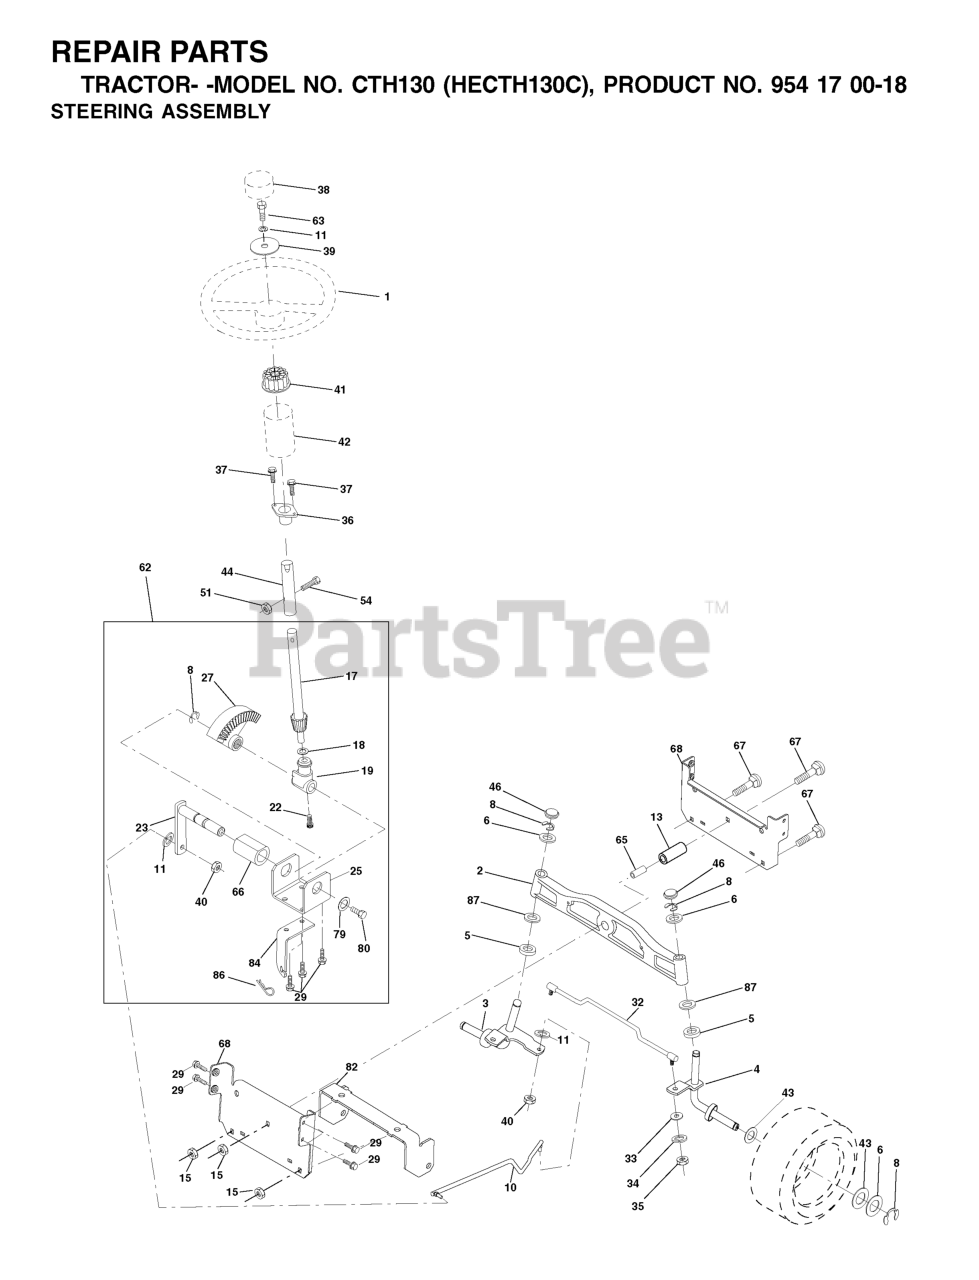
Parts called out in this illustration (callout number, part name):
1	STEERING WHEEL
2	AXLE ASM
3	SPINDLE.ASM.LH.15"TIRES
4	SPINDLE.ASM.RH.15"TIRES
5	THRUST WASHER
10	DRAGLINK.15".TIRES
11	WASHER, LOCK 3/8
13	TUBE, PIVOT AXLE
15	NUT
17	SHAFT ASM STEERING
18	THRUST WASHER
19	STEERING SHAFT SUPPORT
22	SCREW.HX.WSH.HD
23	SHAFT ASSY PITTMAN
25	BRACKET STEERING
27	GEAR.SECTOR
29	SCREW 3/8-16X3/4
32	ROD.ASM.TIE.BALL.JOINT.NOVAN
33	WASHER M
34	WASHER.LOCK.HVY.HLCL.SPR.5/16
35	NUT, CROWNLOCK
36	BUSHING, STEERING
37	SCREW.TT.#10-32X.5.3/8.FLANGE
38	CAP.WHEEL.STEERING.GREY
39	Washer 13/32 x 1-1/20 x 11 Gauge
40	GRIPCO NUT
41	STEERING WHEEL ADAPTOR
42	BOOT STEERING
44	EXT SHAFT STEERING
46	CAP.SPINDLE.BLACK
51	NUT.71038.31-18.HEX.NYLOCK
54	BOLT.5/16-18X1-1/4 FULL.THREAD
62	Kit, Steering Assembly, Service
65	SPACER BRACE AXLE
66	BEARING ARM
67	BOLT
68	BRACE.AXLE.15"TIRES
79	WASHER
80	BOLT.HX.NYLON3/8-16X
82	BRACKET
84	Bracket Cable Clutch Chassis
86	SPRING.RETAINER.YELLOW.ZINC
87	WASHER, FLAT .781 X 1 1/2"
